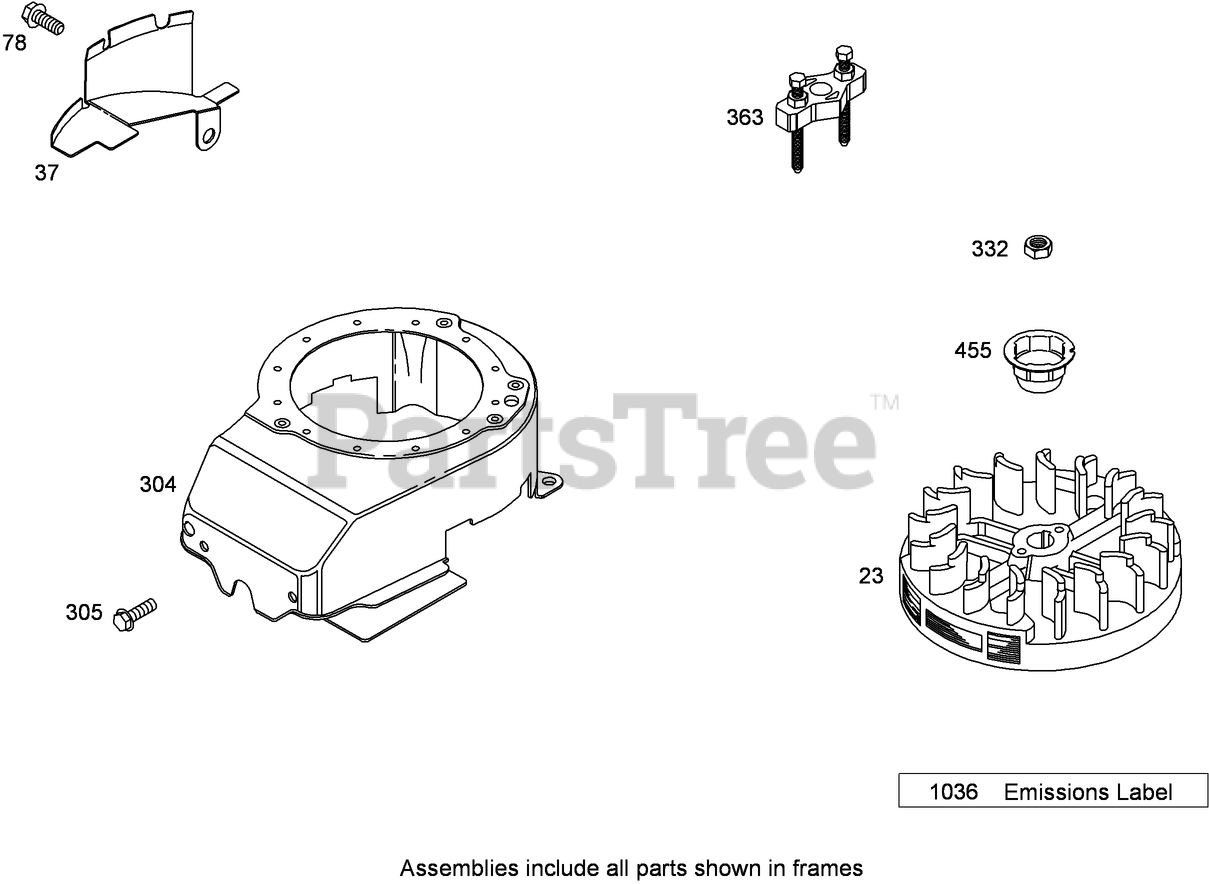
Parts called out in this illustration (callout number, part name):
23	Flywheel
37	Guard-Flywheel
78	Screw
304	Housing-Blower
305	Screw
332	Nut
363	Puller-Flywheel
455	Gasket-Passage, Breather
1036	Loose Parts Package
